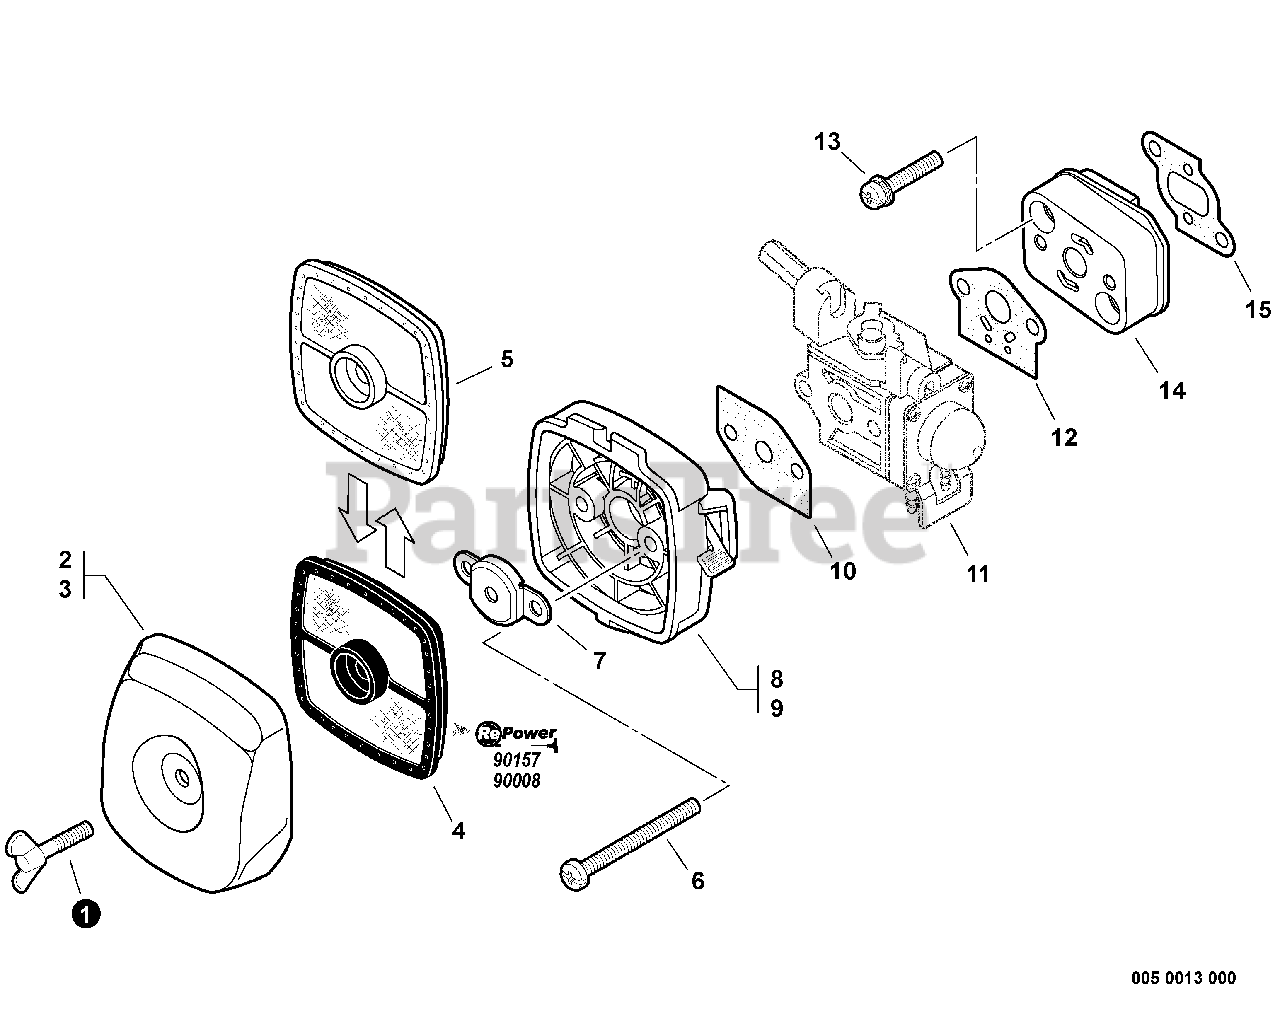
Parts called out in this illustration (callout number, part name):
1	BOLT, WING 5×20
2	COVER, AIR FILTER - GRAY
3	COVER, AIR FILTER - BLACK
4	FILTER, AIR - DOUBLE LAYER
5	FILTER, AIR - SINGLE LAYER
6	SCREW 5×60
7	PLATE, PREVENT
8	CASE, AIR FILTER - GRAY
9	CASE, AIR FILTER - BLACK
10	GASKET, INTAKE
11	CARBURETOR
12	GASKET, CARBURETOR
13	BOLT 5×25
14	INSULATOR, INTAKE
15	GASKET, INTAKE
16	TUNE-UP KIT
17	FILTER KIT - REPOWER
